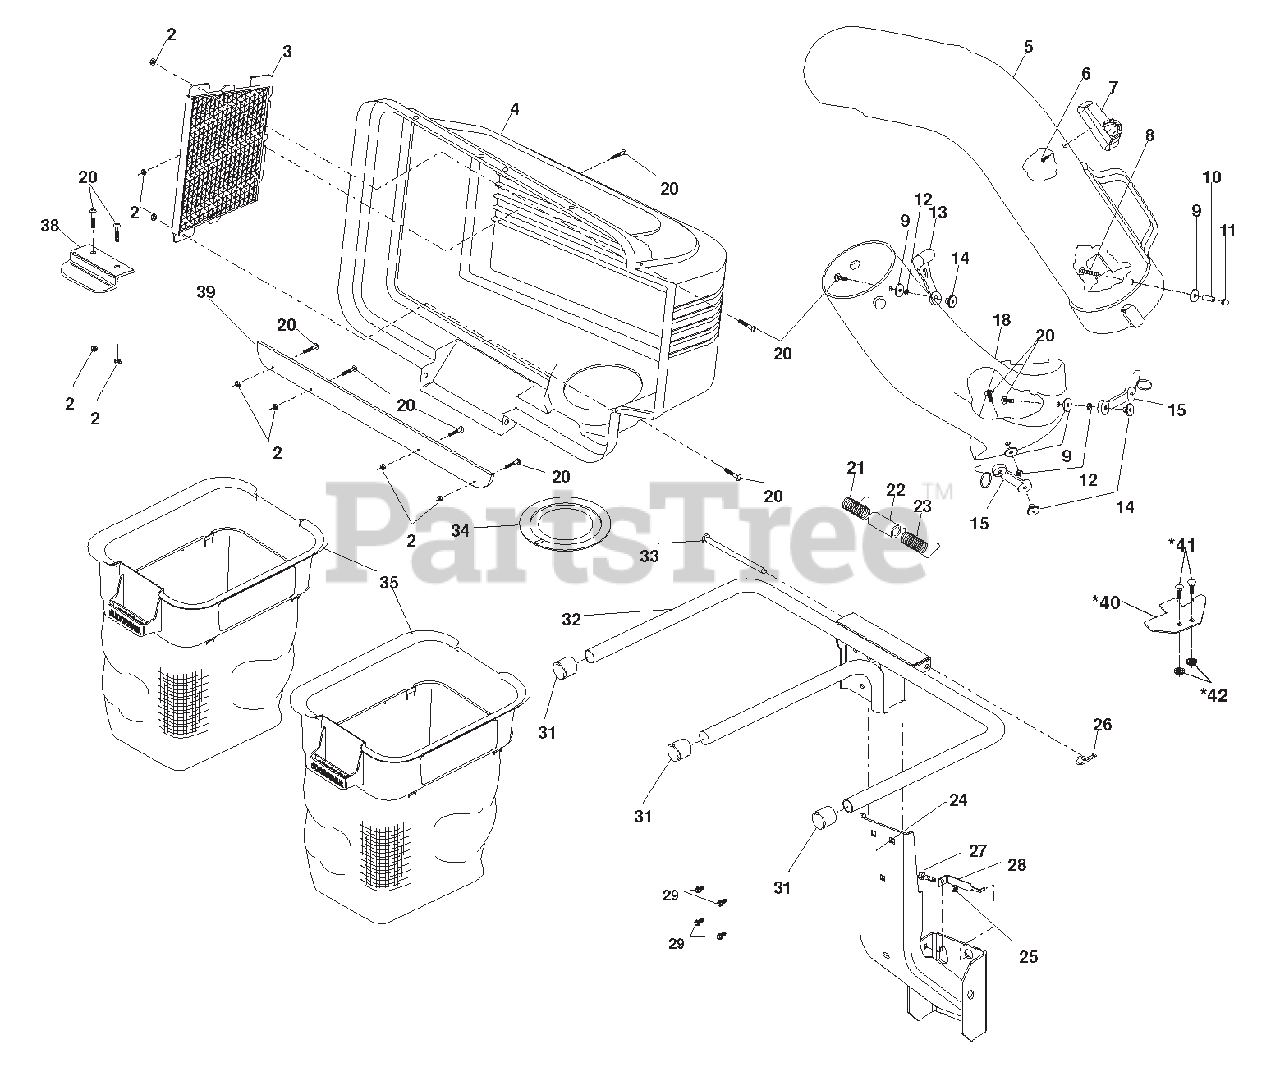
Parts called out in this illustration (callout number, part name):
2	Nut, Crown lock #10-24
3	SCREEN, BAGGER COVER
4	Cover Assembly (Includes 3, 38
5	UPPER BAGGER CHUTE
6	Screw, Special #10-14x1/2
7	FULL BAG INDICATROR
8	SCREW #10-24 X 1-1/8"
9	Washer 3/16x3/4x16 Ga.
10	Spacer, Split
11	ACORN NUT #10-24
12	LOCK WASHER
13	CHUTE LATCH, HUSQ BAGGER
14	Nut, Weld
15	Latch Hook
18	Chute, Lower
20	Screw #10-24 x 5/8
21	Spring, Cover L.H. (black)
22	Spacer, Cover
23	Spring, Cover R.H. (gray)
24	Support Assemble
25	Lock Nut 1/4-20
26	RETAINER.SPRING
28	Bracket, Lock
29	Bolt, Shoulder 5/16-18
31	Clip, Hairpin
32	Bagger, Frame
33	Pin, Hinge
34	GASKET, BAGGER COVER
35	Container
38	Latch Handle, Cover
39	Strip, Reinforcement
40	Plate, Reinforcement
41	Bolts, Carriage 1/4
42	Locknuts, Hex, Flanged
